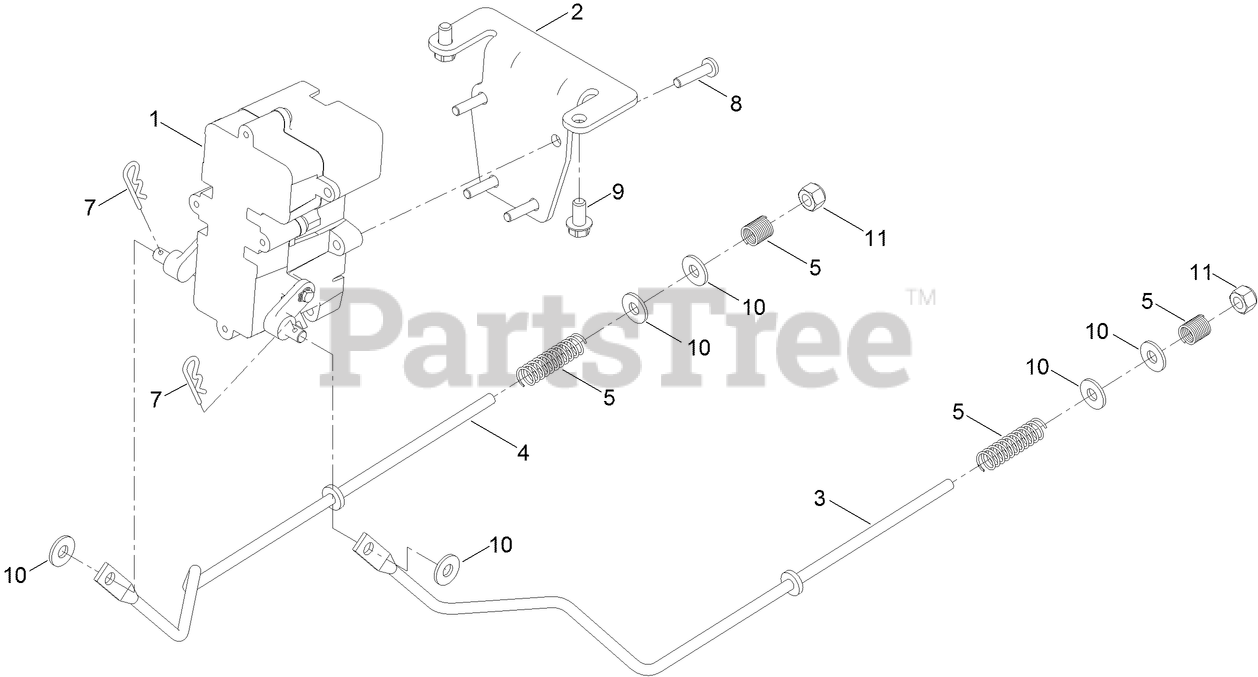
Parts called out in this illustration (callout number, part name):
1	BRAKE BOX ASM
2	BRACKET-MOUNT, BRAKE
3	ROD-BRAKE, LH
4	ROD-BRAKE, RH
5	SPRING-COMPRESSION
8	SCREW-PPH
9	SCREW-HWH
10	WASHER
11	NUT-LOCK, NI
